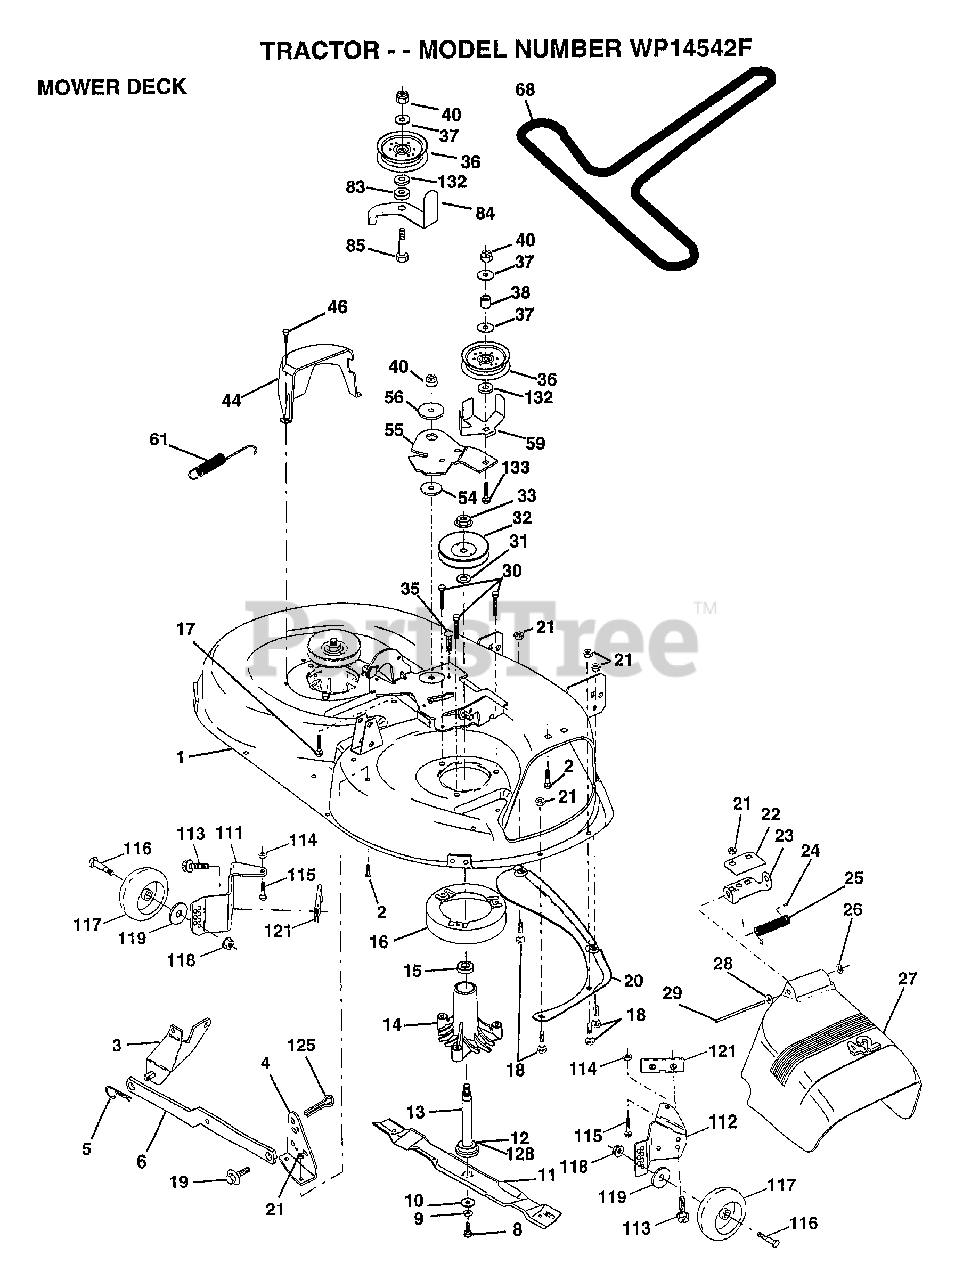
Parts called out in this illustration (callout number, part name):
1	"HOUSING ASSY.42"""
2	BOLT
3	BRKT ASM SWAY BAR
4	BRKT DECK SW BAR
8	BLADE BOLT
10	WASHER.HARD.BLADE
11	"BLADE.42"" HIPERF"
12	BEARING.BALL
14	HSG ASM MANDREL
15	BEARING
16	STRIPPER RND MWR
17	BOLT CARRIAGE
18	BOLT
19	BOLT SHD 5/16-18
20	BAFFLE VORTEX 42
22	STIFFENER BRKT
23	DEFLECTOR BRKT
24	CAP-SLEEVE LT
25	SPRING TORSION
26	NUT PUSH M
27	DEFLECTOR.SHIELD
28	WASHER
29	HINGE ROD
30	"SCREW-THD ROLL,WA"
31	WASHER
32	PULLEY.MANDREL.42
35	XMAS TREE FASTNER
36	FLAT IDLER PULLEY
37	WASHER
44	GUARD MAND LH BLK
46	SCREW.1/4-20X5/8
54	HARDENED WASHER
56	SPACER RETAINER
59	GUARD IDLER TUV
61	SPRING.EXTENSION
68	BELT.V.T-PATH
83	WASHER
84	"KEEPER-BELT,FIXED"
85	BOLT
111	BRACKET.GWHL.LH.
112	BRACKET.GWHL.RH.
113	SCREW
116	BOLT M
117	WHEEL.GUAGE
118	LOCKNUT
119	WASHER
121	BRACKET.EXTRD.GWL
125	COTTER PIN
128	WASHER.FELT.
132	WASHER GT
133	BOLT
